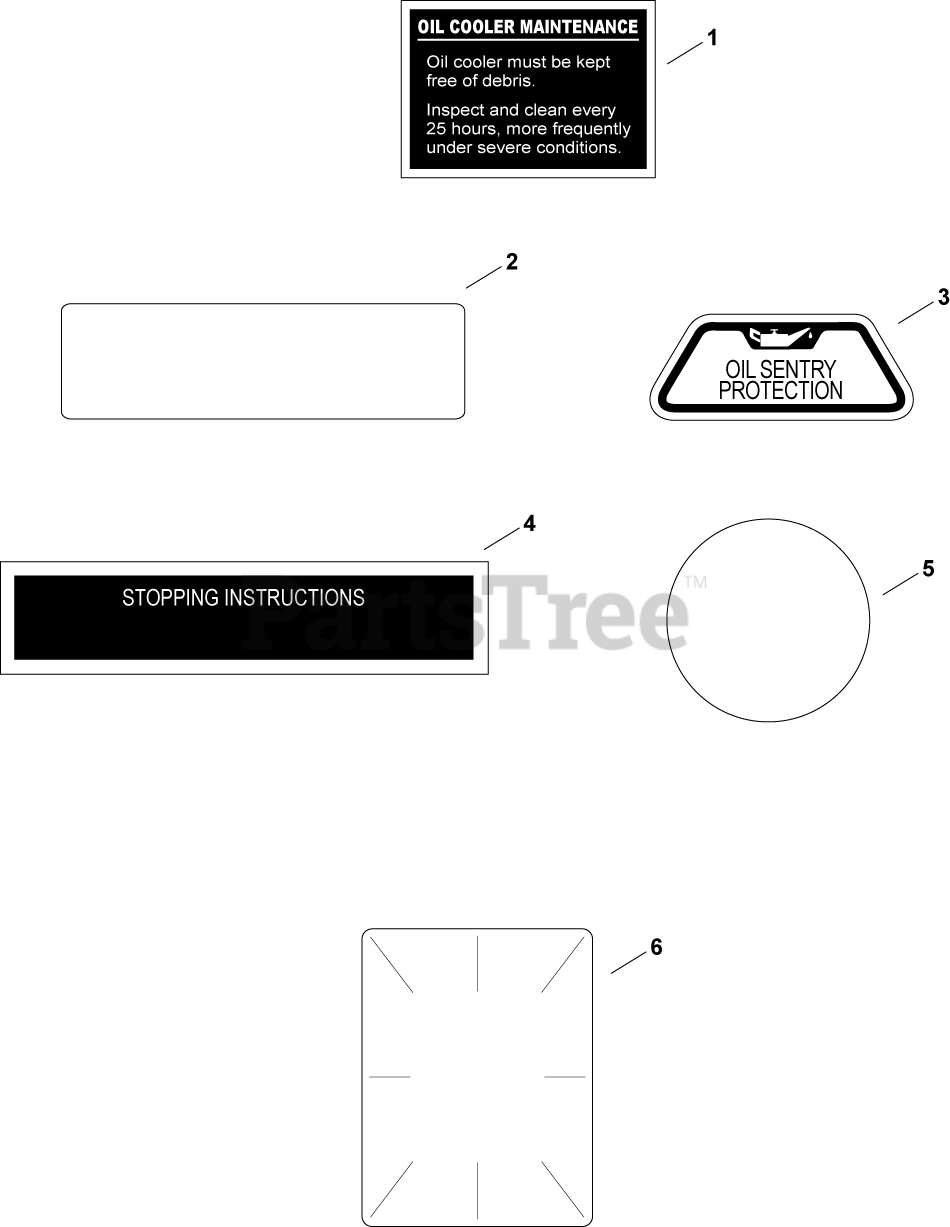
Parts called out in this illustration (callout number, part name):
1	DECAL, OIL COOLER - (#DSC)
2	DECAL, 25 HP
3	DECAL, OIL SENTRY - (#DSC)
4	DECAL, STOPPING INSTRUCTION
5	LABEL, (ROUND KOHLER GOLD)-USE 24 113 18
6	DECAL, CLEAR LAMINATE USE 25 113 70-S
